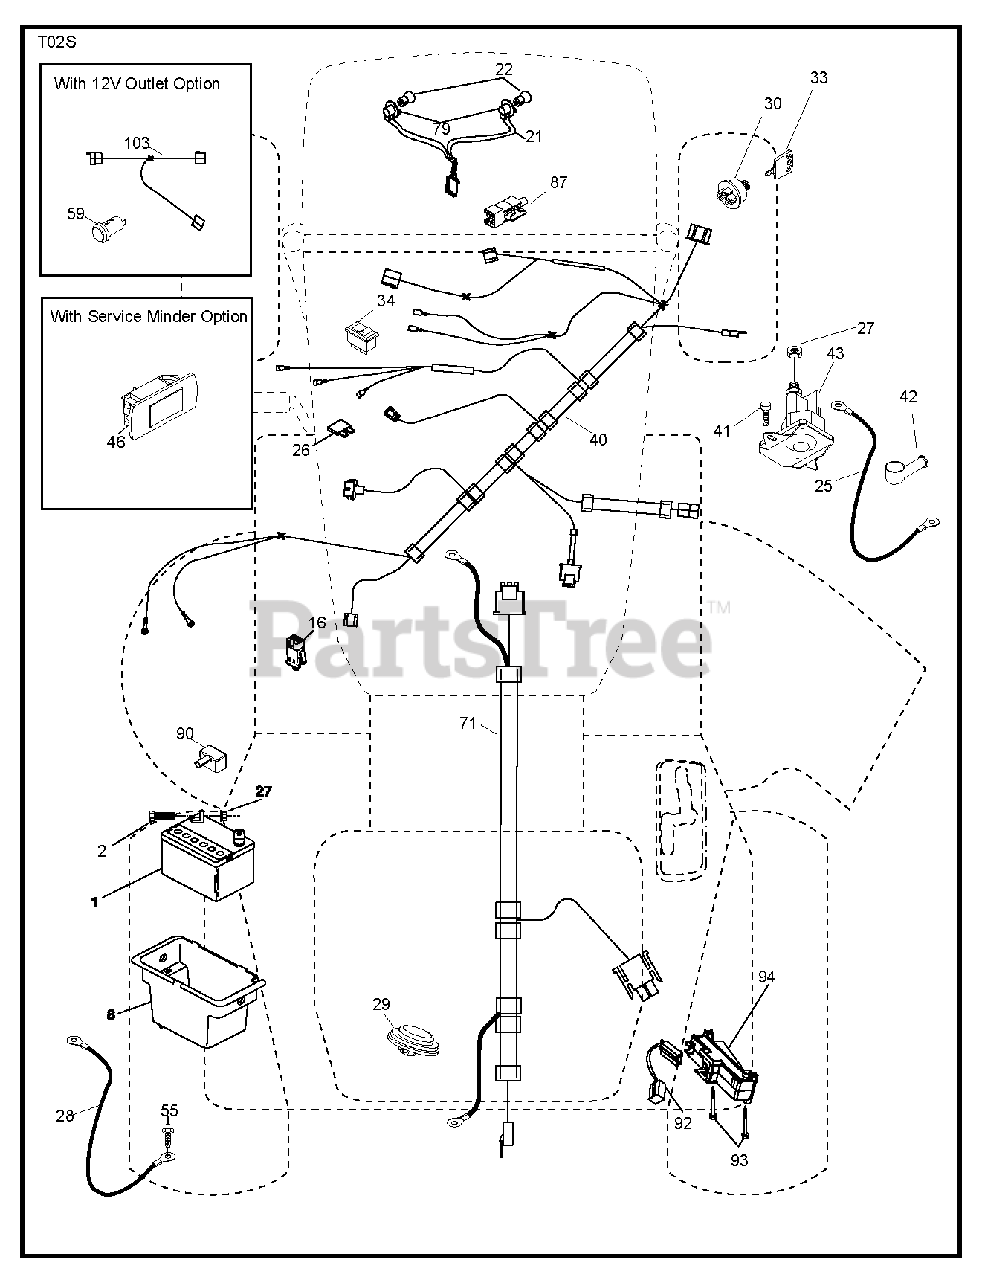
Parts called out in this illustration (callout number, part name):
1	REPL BY 532 12 38-99
2	BOLT.HEX.1/4.X.3/4.DICHROMATE
8	BOX.BATTERY.MNT.REAR.L
16	SWITCH INTERLOOK PUSH-IN
21	HARNESS ASSY LIGHT
22	LIGHTBULB
25	CABLE.STARTER.6GA.BL/RED.14.
26	FUSE 20AMP
27	NUT
28	CABLE.BLACK.18"REAR.BA
29	SWITCH.SEAT.DELTA.OPC.
30	SWITCH.IGN.DELTA.W.LGH.ROS
33	KEY.CHAIN.BLISTER.PACK.GEN.INT
34	SWITCH LT
40	HARNESS IGN. DASH
41	SCREW
42	TERMINAL COVER
43	SOLENOID.W/BRASS.PLUNGER
55	SCREW 5/16"
71	HARNESS.IGN.CHASS.TEX.REAR.BAT
79	BULB HOLDER ASM.
87	SWITCH.INTRLCK.CLUTCH.
90	COVER.TERMINAL.BATTERY
92	HARNESS.PIGTAIL.CONSLE
93	SCREW.PLASTITE
94	MODULE.REVERSE.ROS
